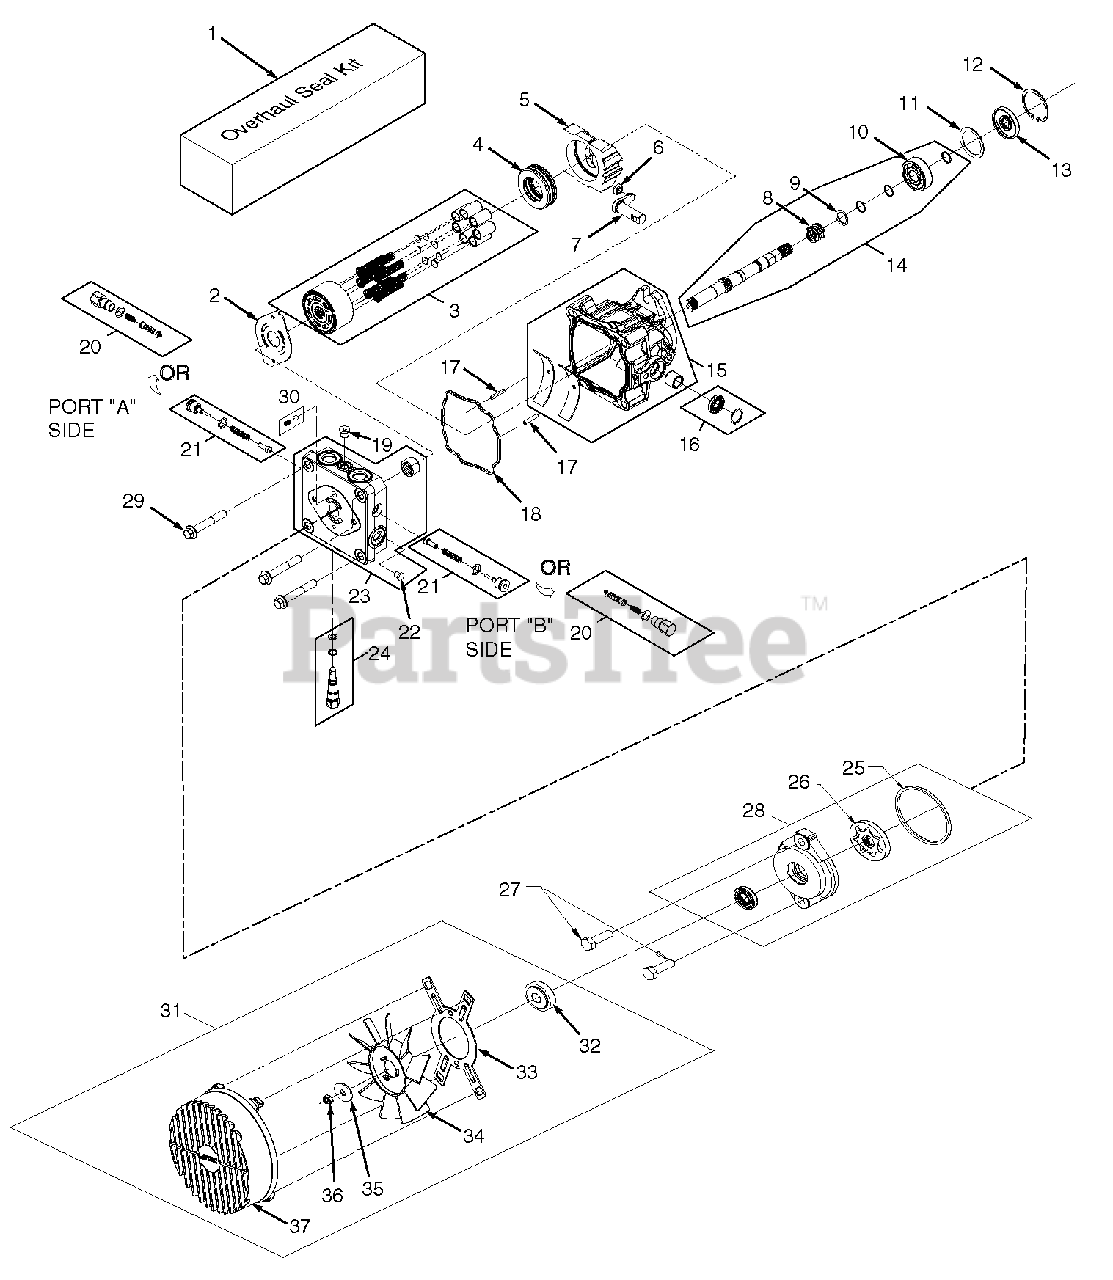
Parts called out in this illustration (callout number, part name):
1	Overhaul Seal Kit
2	Valve Plate
3	Cylinder Block Kit - 16cc
4	Thrust Ball Bearing Assembly
5	Variable Swashplate
6	Slot Guide
7	Trunnion Arm
8	Block Spring
9	Block Thrust Washer
10	Shaft Ball Bearing
12	Retaining Ring
14	Kit, Pump Shaft
15	Housing Kit
16	Trunnion Seal Kit
18	O-Ring
19	Straight Thread Plug
20	Shock Valve Kit (.031 Orifice)
21	Shock Valve Kit (.024 Orifice)
22	Straight Thread Plug
23	End Cap Kit
24	Bypass Valve Kit
26	Gerotor Assembly (.19 cu.in./rev.)
27	Socket Head Cap Screw (M8 x 1.25-25mm)
28	Charge Pump Kit (.19 STD. Splined)
29	Hex Screw, Flanged Head (M10 x 1.50-65mm)
30	Charge Relief Kit
31	Fan Kit
33	Bracket, Shroud
35	Washer
37	Shroud
